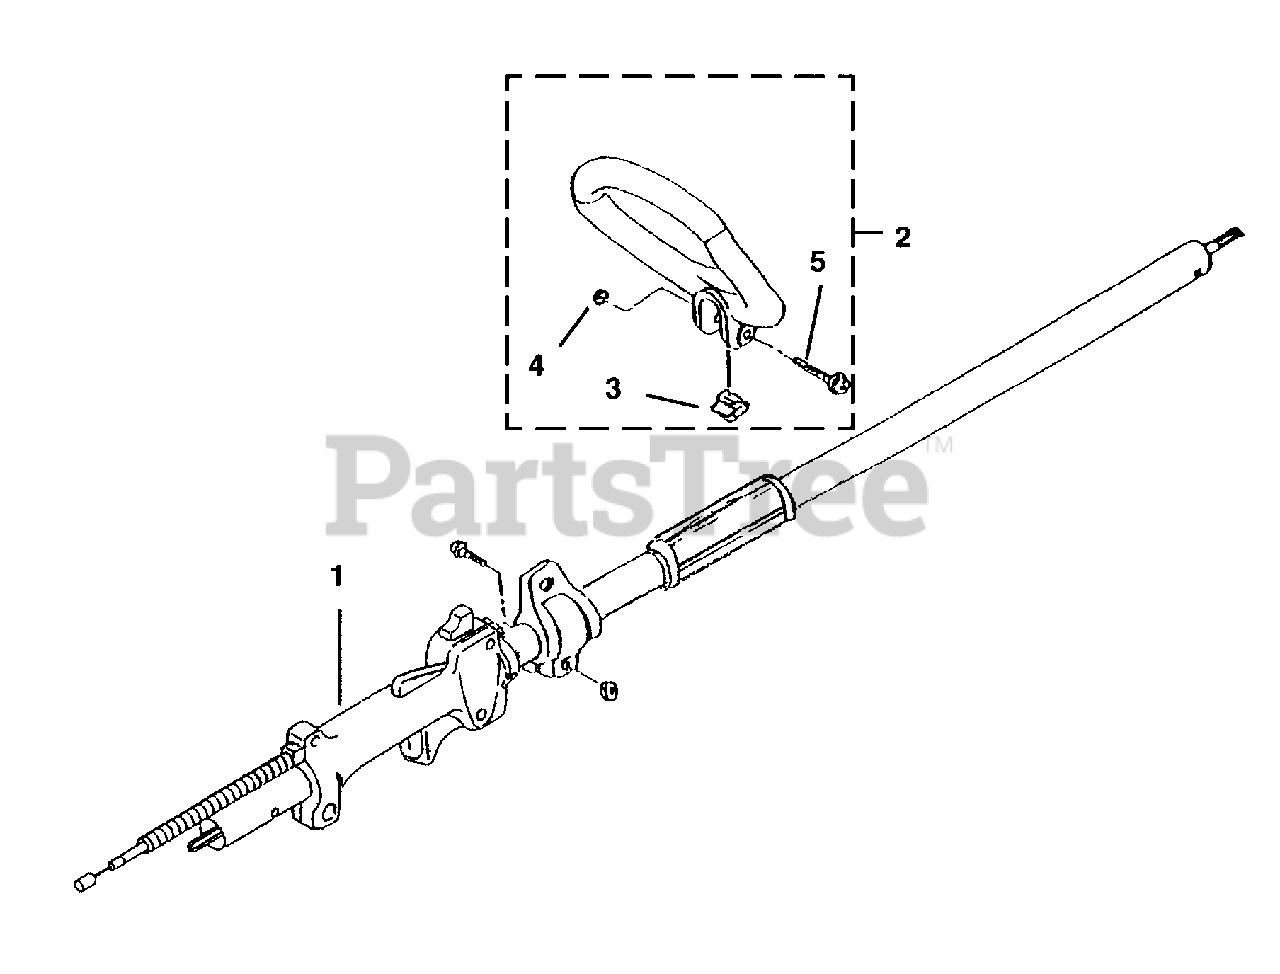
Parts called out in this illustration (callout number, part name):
1	CONTROL LEVER ASSEMBLY
2	HANDLE ASSEMBLY
4	NUT-Flange (M6)
5	BOLT-Cross Recess
